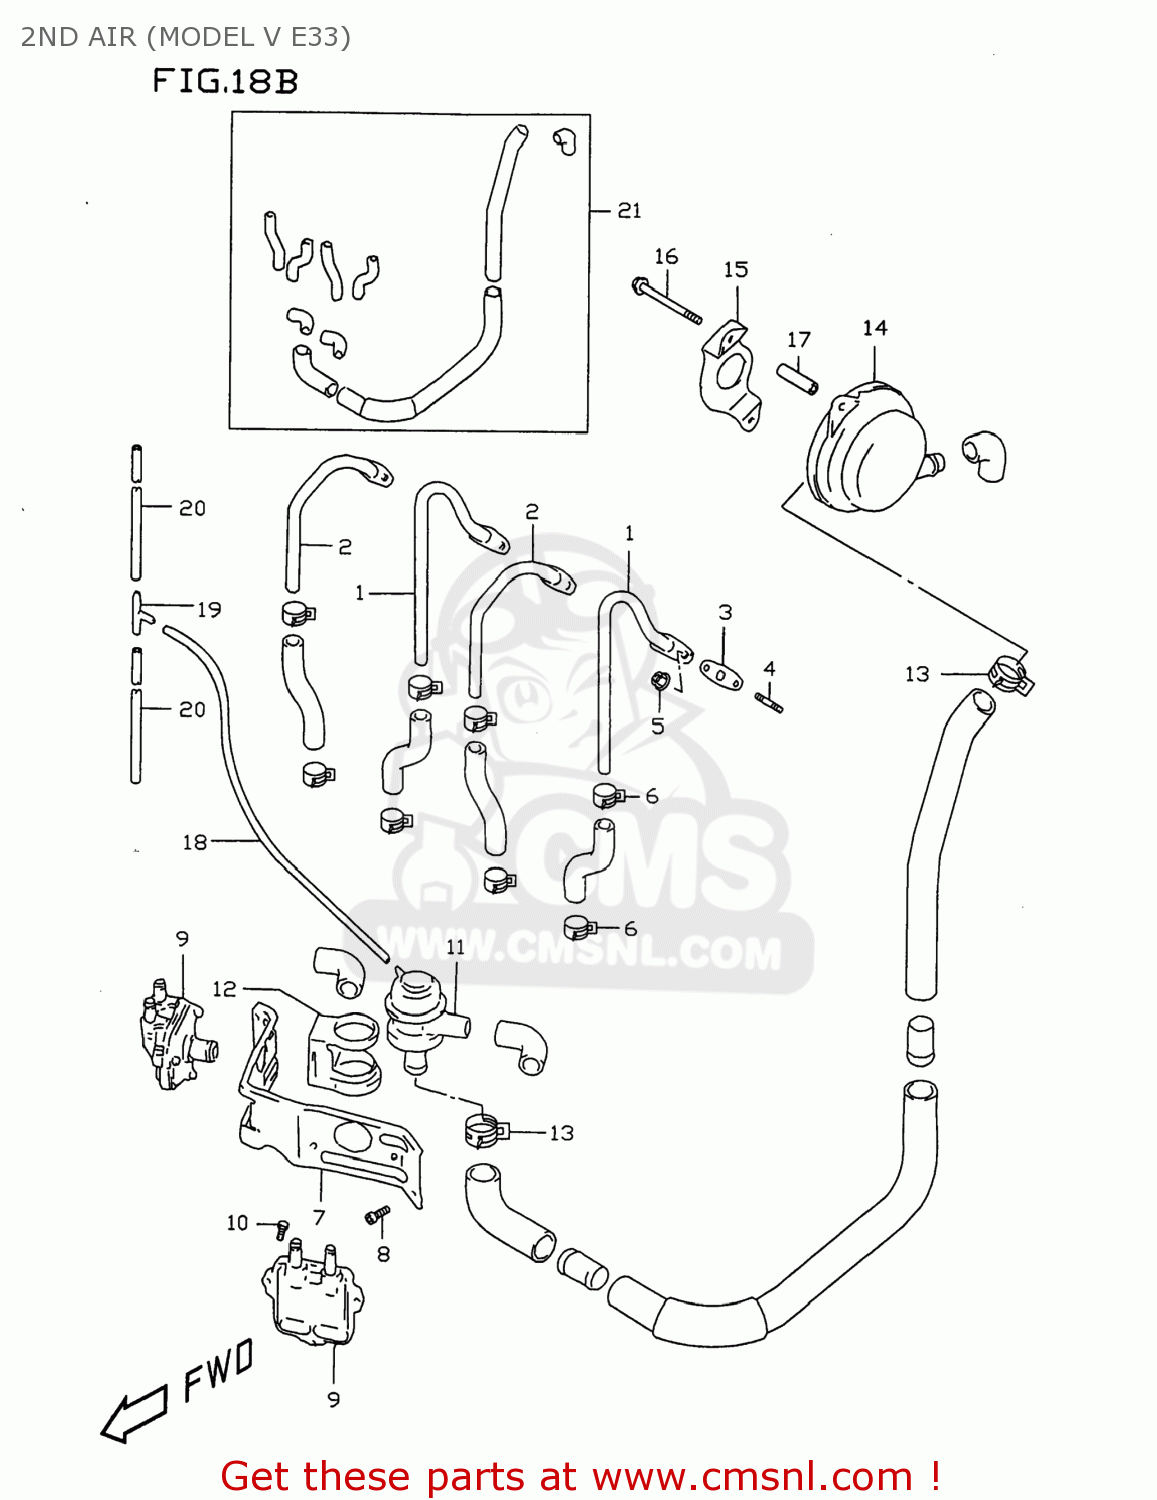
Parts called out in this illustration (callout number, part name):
1	PIPE COMP,SECOND AIR NO.1
2	PIPE COMP,SECOND AIR NO.2
3	GASKET,SECOND AIR PIPE (N (NAS)
4	STUD BOLT
5	NUT
6	CLIP
7	BRACKET COMP,SECOND AIR
8	BOLT 6X12
9	VALVE ASSY,2ND AIR REED
10	BOLT
11	VALVE ASSEMBLY,SECOND AIR SWITCH
12	CUSHION,2ND AIR VALVE
13	CLAMP
14	CLEANER ASSEMBLY,SECOND AIR
15	HOLDER,SECOND AIR CLEANER
16	BOLT
17	SPACER(6.5X10.5X40)
18	HOSE(4X7X600)
19	JOINT,3 WAY
20	HOSE(5X10X600)
21	HOSE SET,2ND AIR
